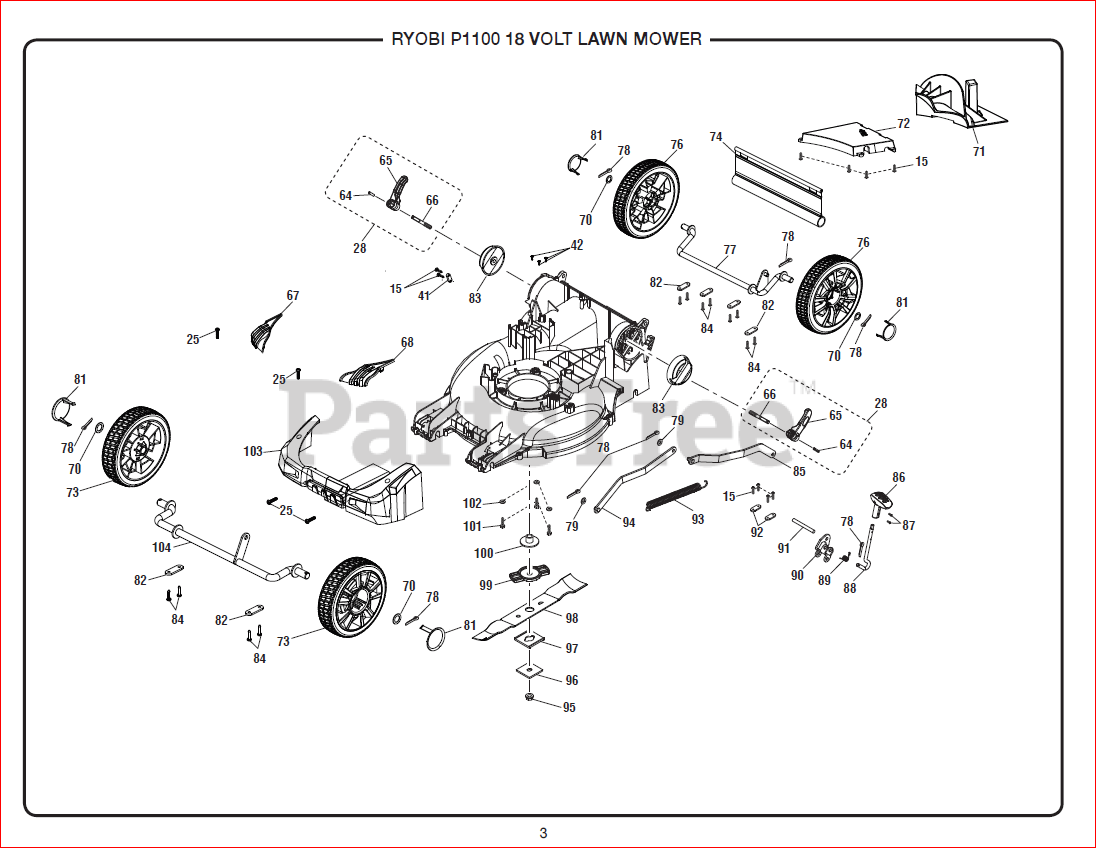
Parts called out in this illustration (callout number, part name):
15	Screw (M4 x 16 mm, T20 Torx Pan Hd.).
25	Screw (M4 x 20 mm, T20 Torx Pan Hd. S.T.)
28	Handle Lock Assembly
41	Wire Press Plate
42	Screw (M4.2 x 12 mm, T20 Torx Pan Hd.)
64	Spring Pin
65	Adjust Height Handle
66	Quick Lock Press
67	Grass Protector (Right)
68	Grass Protector (Left)
70	Washer (ID13.5 x OD20 x 1t)
71	Mulching Plug
72	Rear Cover
73	Front Wheel w/Bearing & Cap 6 in.
74	Rear Skirt
76	Rear Wheel w/Bearing & Cap 8 in.
77	Rear Wheel Axle
78	Cotter PinÏ? (2.5)
79	Washer (ID8.4 x OD18 x 1t)
81	Wheel Cover (Before Serial Number EU18234D020307)
82	Axle Pressure Plate
83	Quick Lock Press Block
84	Screw (M4 x 18 mm, T20 Torx Pan Hd.)
85	Rear Lift Rod
86	Height Adjustment Handle
87	Screw (M3 x 9 mm, Flat Hd.)
88	Height Adjustment Lever
89	Torsion Spring (Height Adjustment)
90	Adjustment Height Bracket
91	Axle (Height Adjustment)
92	Pressure Plate (Height Adjustment)
93	Rentention Spring
94	Front Lift Rod
95	Blade Nut (M10 x 1.25, Hex Flange Hd.)
96	Metal Blade Retainer
98	Blade (16 in.)
99	Blade Holder
100	Motor Shaft Bushing
101	Bolt (M6 x 26 mm, Hex Hd.)
102	Washer (ID6.2 x OD15 x 0.08t)
104	Front Wheel Axle
